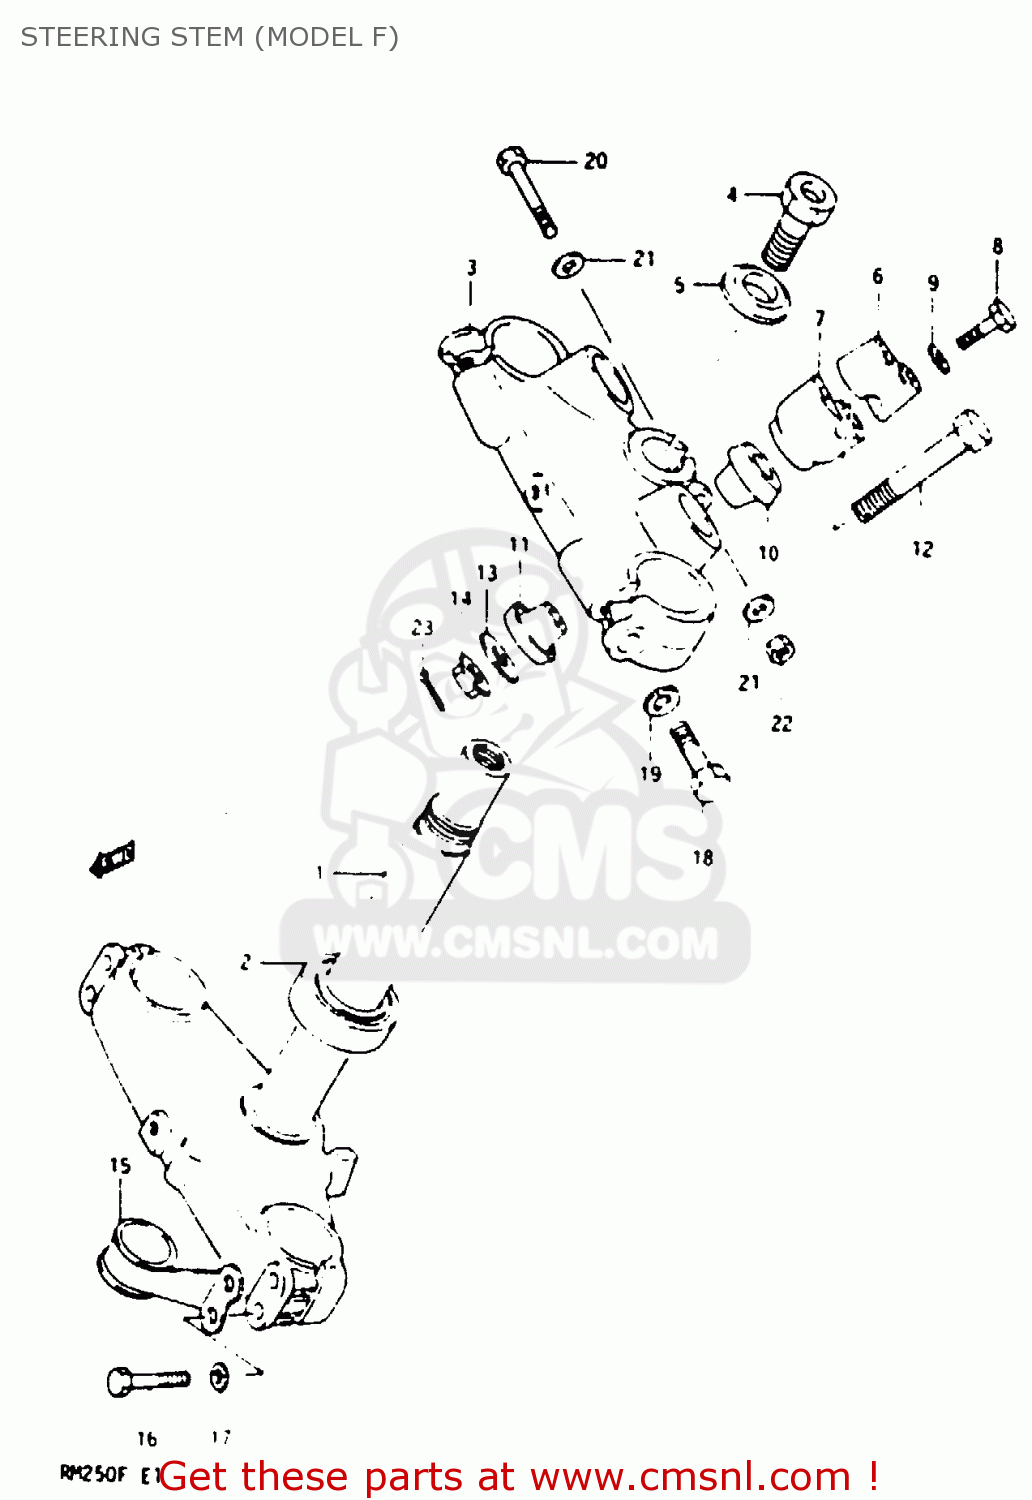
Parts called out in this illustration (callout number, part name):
1	STEM,STEERING
2	BEARING
3	HEAD,STEERING STEM
4	BOLT
5	WASHER
6	HOLDER,HANDLEBAR
7	HOLDER,HANDLE LWR
8	BOLT
9	WASHER,LOCK,8.
10	DAMPER,UPR
11	DAMPER,LWR
12	BOLT
13	WASHER,HANDLEBAR HOLDER
14	NUT
15	GUIDE,CABLE
16	BOLT 8X40
17	WASHER,LOCK,8.
18	BOLT
19	LOCK WASHER
20	BOLT 8X50
21	WASHER
22	NUT
23	COTTER PIN
